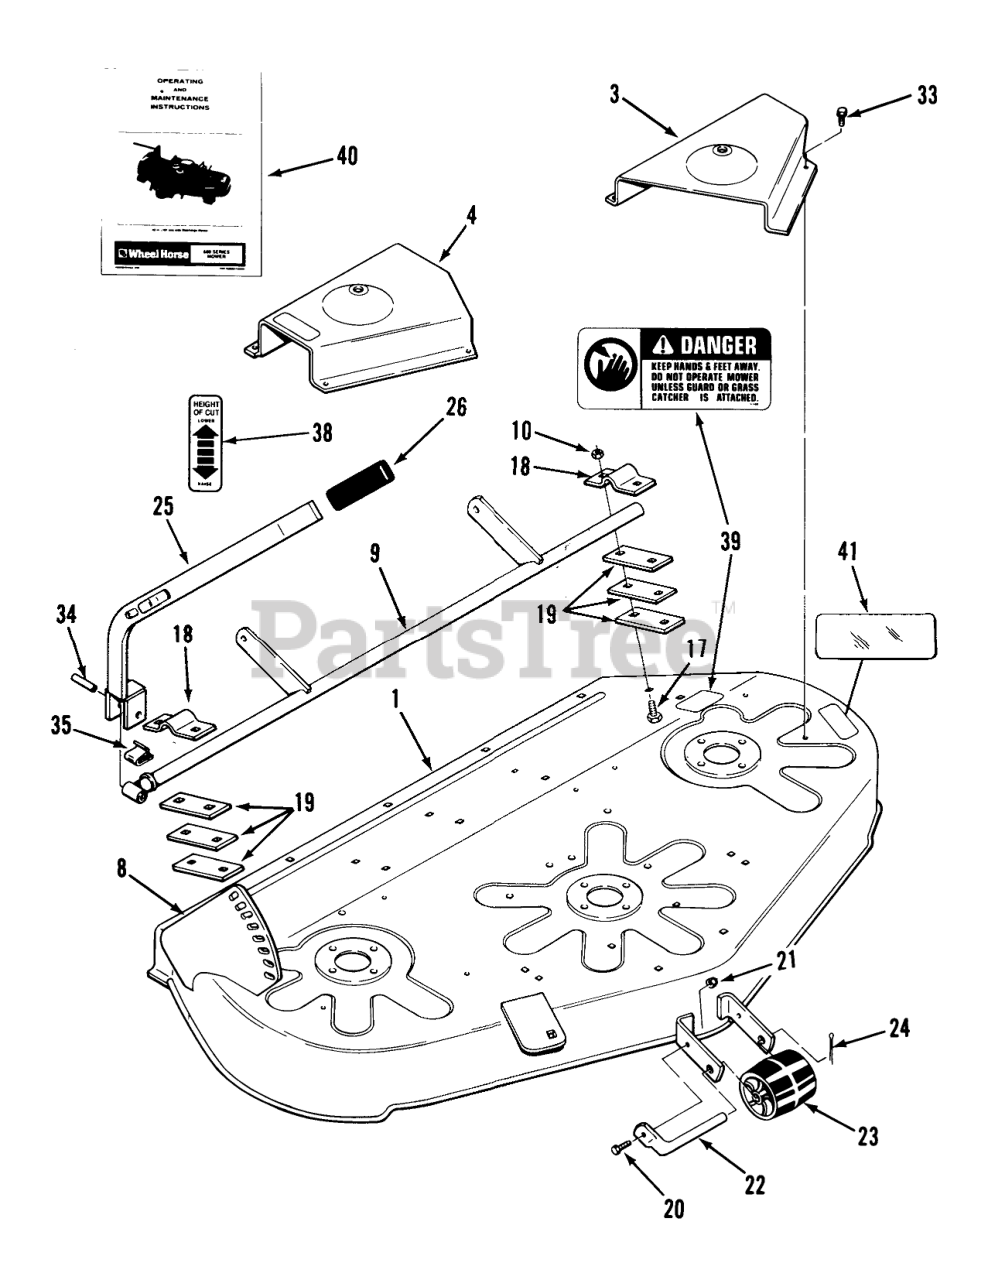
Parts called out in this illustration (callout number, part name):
9	WASHER
10	SPACER
18	SPACER
21	SPACER
22	SPRING-EXTENSION
33	WLDMT-HANGER ROD
35	Hairpin
36	BUSHING
39	Bracket RH
40	ROD-LIFT
41	SPACER .375 ID X 1.6
